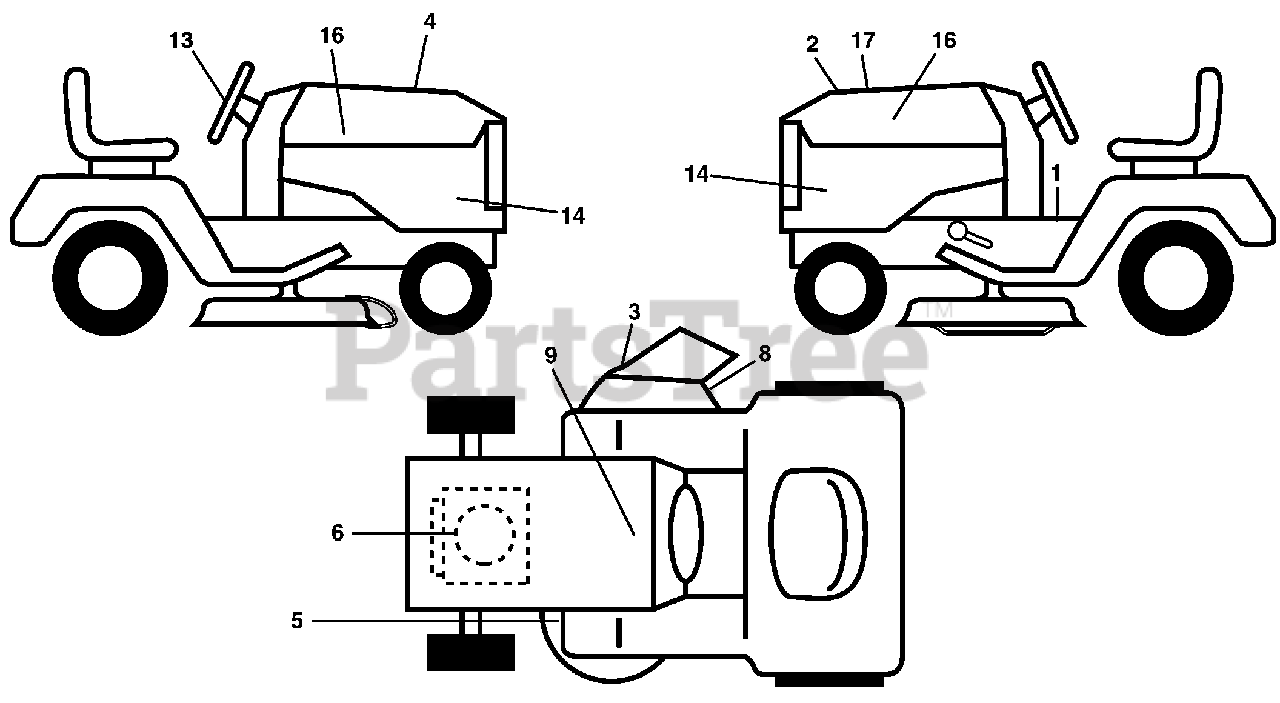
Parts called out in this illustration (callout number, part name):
1	Decal, Operator's
1	Cap, Valve, Tire
2	Decal, Hood Insert
2	Stem, Valve
3	Decal, Warning
3	Rim Assembly, Front
4	Decak, Hood Cust Resp.
4	Tube, Front
5	Decal, Caution
5	Tire, Front
6	Decal, Engine
6	Fitting, Grease
7	Bearing, Flange
8	Decal, Mower Sch.
8	Cap, Axle
9	Decal, Battery Dnge/Poi
9	Tire, Rear
10	Tube, Rear
11	Rim Assembly, Rear
13	Decal, Steering Whl
14	Decal, Panel Side
16	Decal, Hood Logo
17	Decal, Replacement
